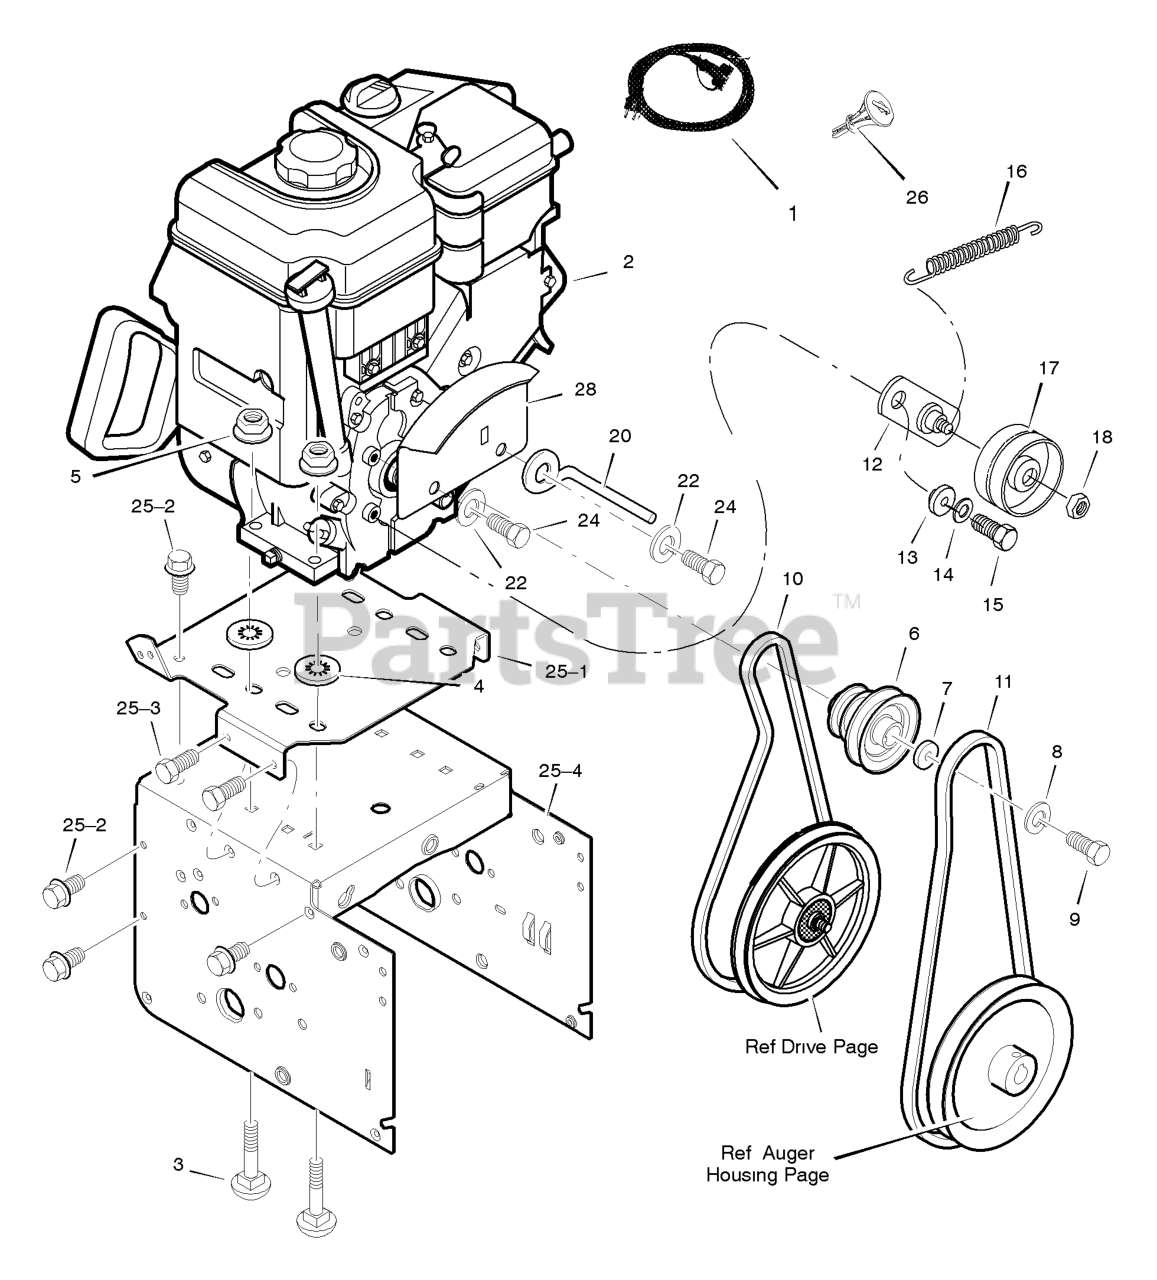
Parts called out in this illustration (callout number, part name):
1	CORD, Electric, 10FT. 110V
2	ENGINE
3	BOLT, CARRIAGE
4	RETAINER, PUSH
6	PULLEY, ENGINE
7	WASHER
8	WASHER
9	SCREW
10	BELT, DRIVE V 4L
11	BELT, AUGER V 3L
12	BRACKET ASSEMBLY, IDLER
13	BUSHING, IDLER BRACKET
14	WASHER, SPLIT
15	SCREW 5/16-24 X 0.75
16	SPRING, IDLER TRACTION DRIVE
17	PULLEY, IDLER
18	NUT, JAM 3/8-16
20	GUIDE, ROD BELT
22	WASHER
25	FRAME ASSEMBLY
25-1	PLATE, ENGINE
25-2	SCREW
25-4	MOTOR BOX
26	KEY, BRIGGS ENGINE
28	SHIELD, BRIGGS ENGINE
